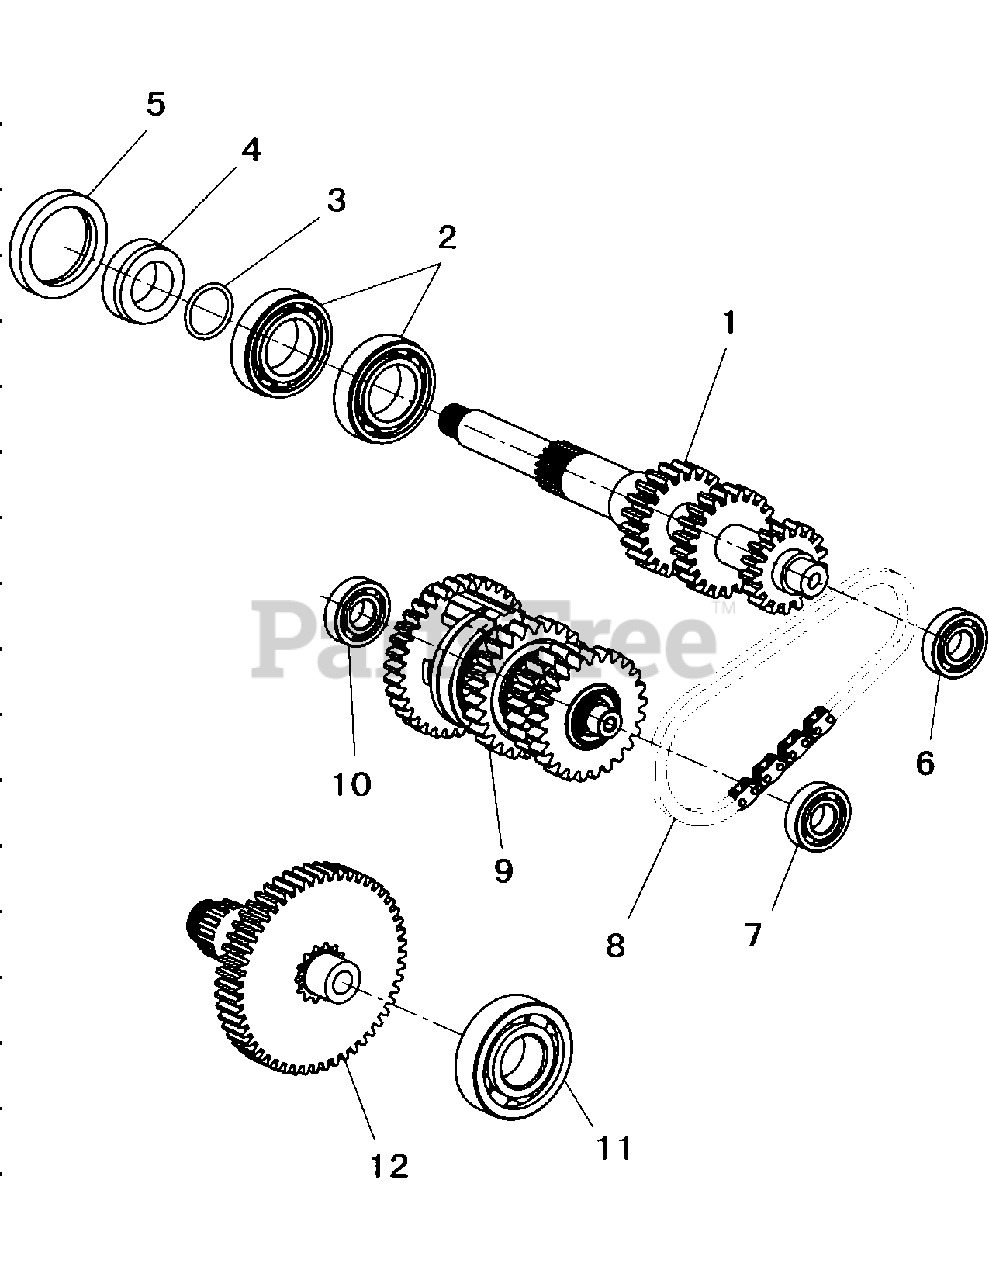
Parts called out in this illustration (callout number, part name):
3	O-Ring 26.1X2.4
4	Collar Sheath-26 X 42 X 14.7
8	Chain-Gear Type M9-9.25-34
9	Middle Shaft-Comp
10	Bearing-6203Dla8
12	Output Shaft Asm
